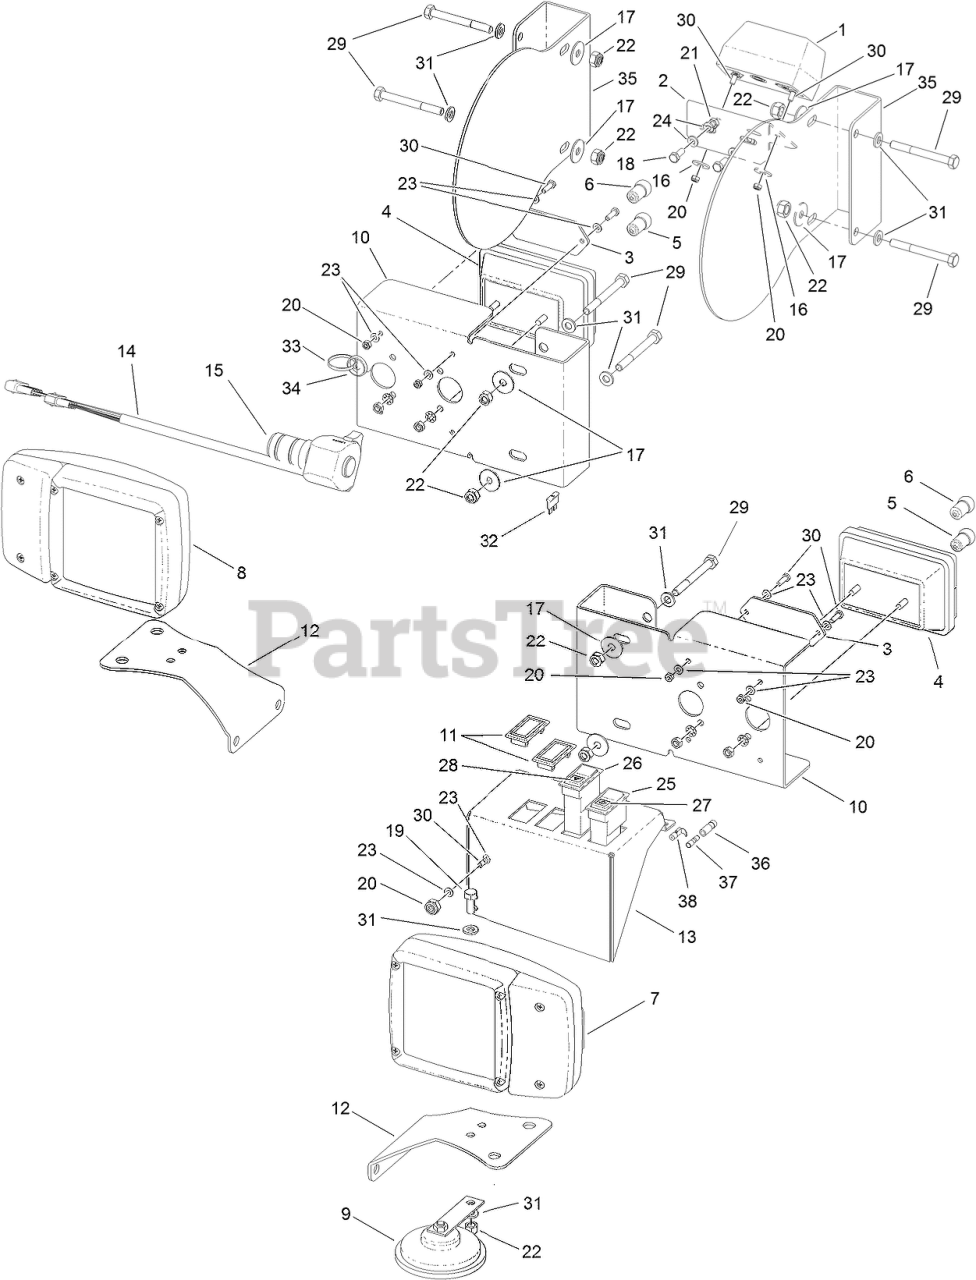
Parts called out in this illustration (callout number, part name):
1	LAMP ASM
3	REFLECTOR-REFLEX, RED
4	LAMP-INDICATOR, REAR
5	BULB-INDICATOR
7	HEADLAMP-INDICATOR, LH
8	HEADLAMP-INDICATOR, RH
10	BRACKET-LIGHT, REAR
11	BLANK-SWITCH
12	BRACKET-LIGHT, FRONT
13	PANEL-SWITCH
14	SWITCH COMBINATION ASM
15	ADAPTOR-SWITCH
16	WASHER
17	WASHER-PLAIN
18	SCREW-HH
19	SCREW-HH
20	NUT-NYLOC
21	NUT-NYLOC
22	NUT-HEX, NI
23	WASHER
24	WASHER-PLAIN
25	SWITCH-DIP/MAIN
26	SWITCH-HAZARD, WARNING
27	LENS-MAIN, LIGHT
28	LENS-HAZARD, WARNING
30	SCREW-HH
31	WASHER-PLAIN
32	FUSE-30A
33	TIE-CABLE
34	TIE-CABLE
35	BRACKET-SPEED DECAL, SIDE
36	CRIMP-FEMALE, BULLET
37	CRIMP-MALE, BULLET
38	CRIMP-TERM., PIGGYBACK RED
